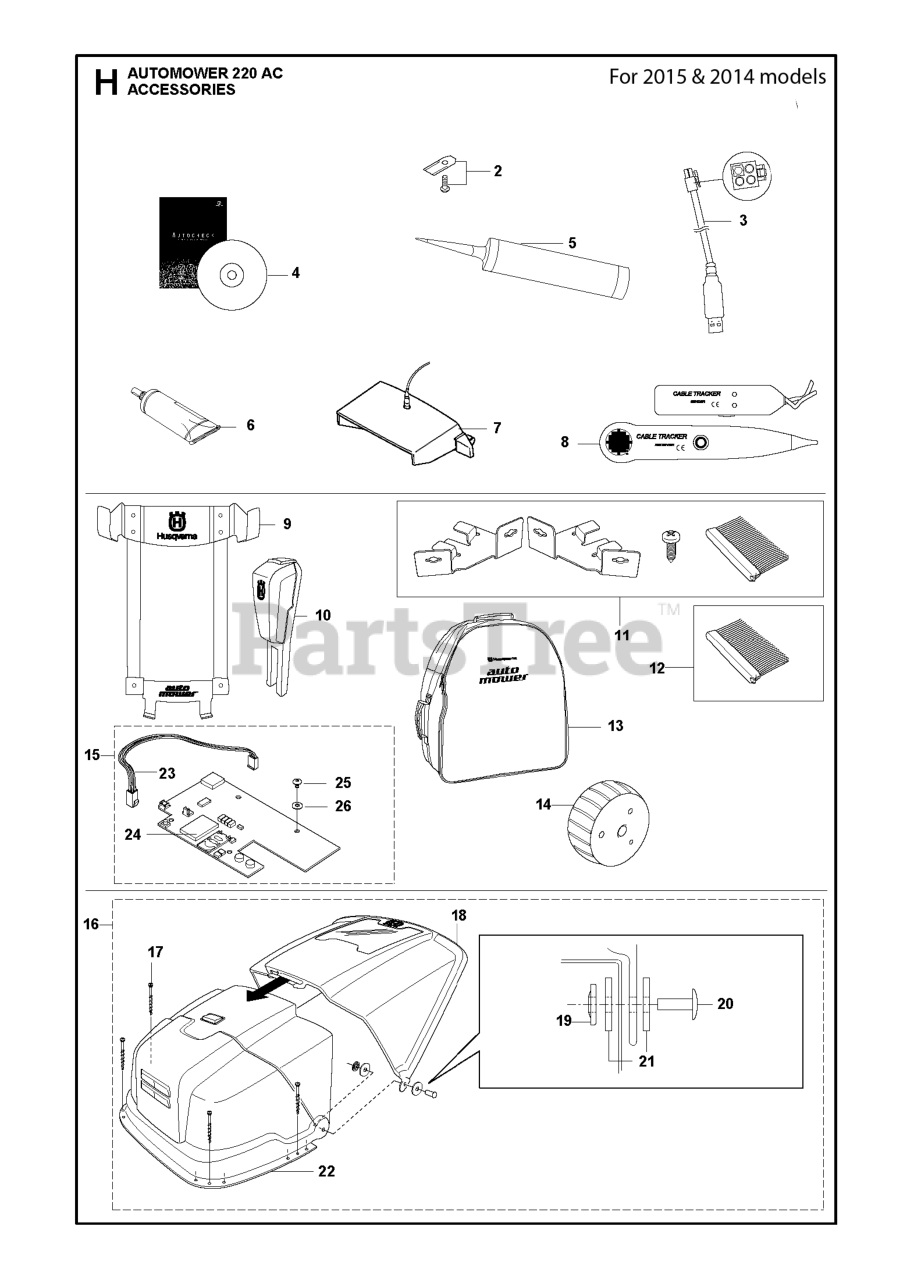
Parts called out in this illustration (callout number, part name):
2	HUS BLADE SET 9 PCS
2	HUS BLADE SET 300 PCS
2	HUS BLADE SET 45 PCS
3	USB SERVICE CABLE
4	DVD AUTOCHECK EXP SERVICE
5	GREASE 300 ML
7	N/A PIN CODE TRANSFER UNIT ADA
8	TEST EQUIPMENT
9	WALL BRACKET ASSY
10	SIGNAL BOOSTER
11	BRUSH KIT BRUSH X6, HOLDER X2,
12	BRUSH WITH CARTON
14	HEAVY FRONT WHEEL KIT INCL PAC
14	WHEEL ASSY
16	AUTOMOWER SHELTER
17	Screws
18	TOP INCL LOGO & WINDOW CHARG
19	LOCK WASHER
20	AXLE CHARGING STATION COVER
22	FRONT CHARGING STATION COVER
23	LOOM LOOM GPS TRACKING MODULE
24	BATTERY GPS TRACKING COMMUNICA
25	SCREW GSM- MODULE
26	WASHER GSM- MODULE
